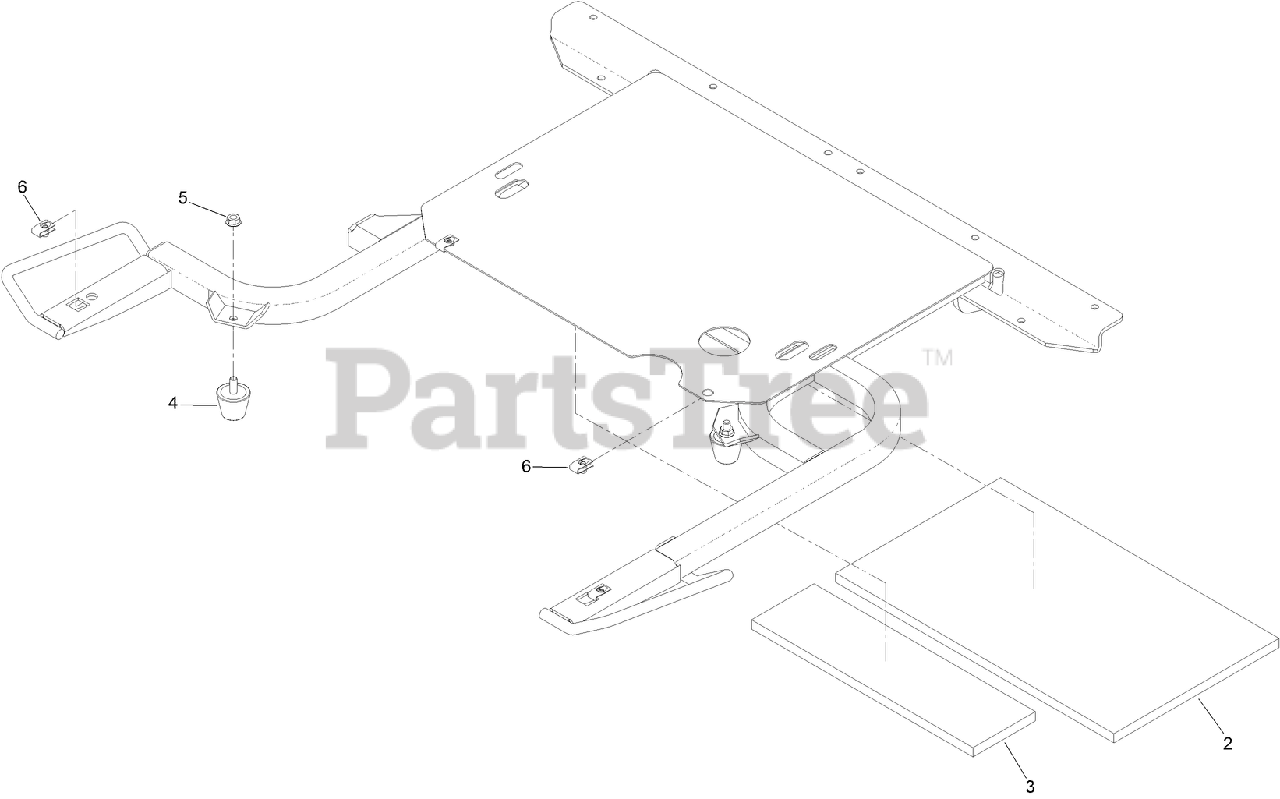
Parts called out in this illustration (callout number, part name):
2	INSULATION-FOAM PAD, REAR
3	INSULATION-FOAM PAD, FRONT
4	BUMPER-RUBBER
5	NUT-HF
